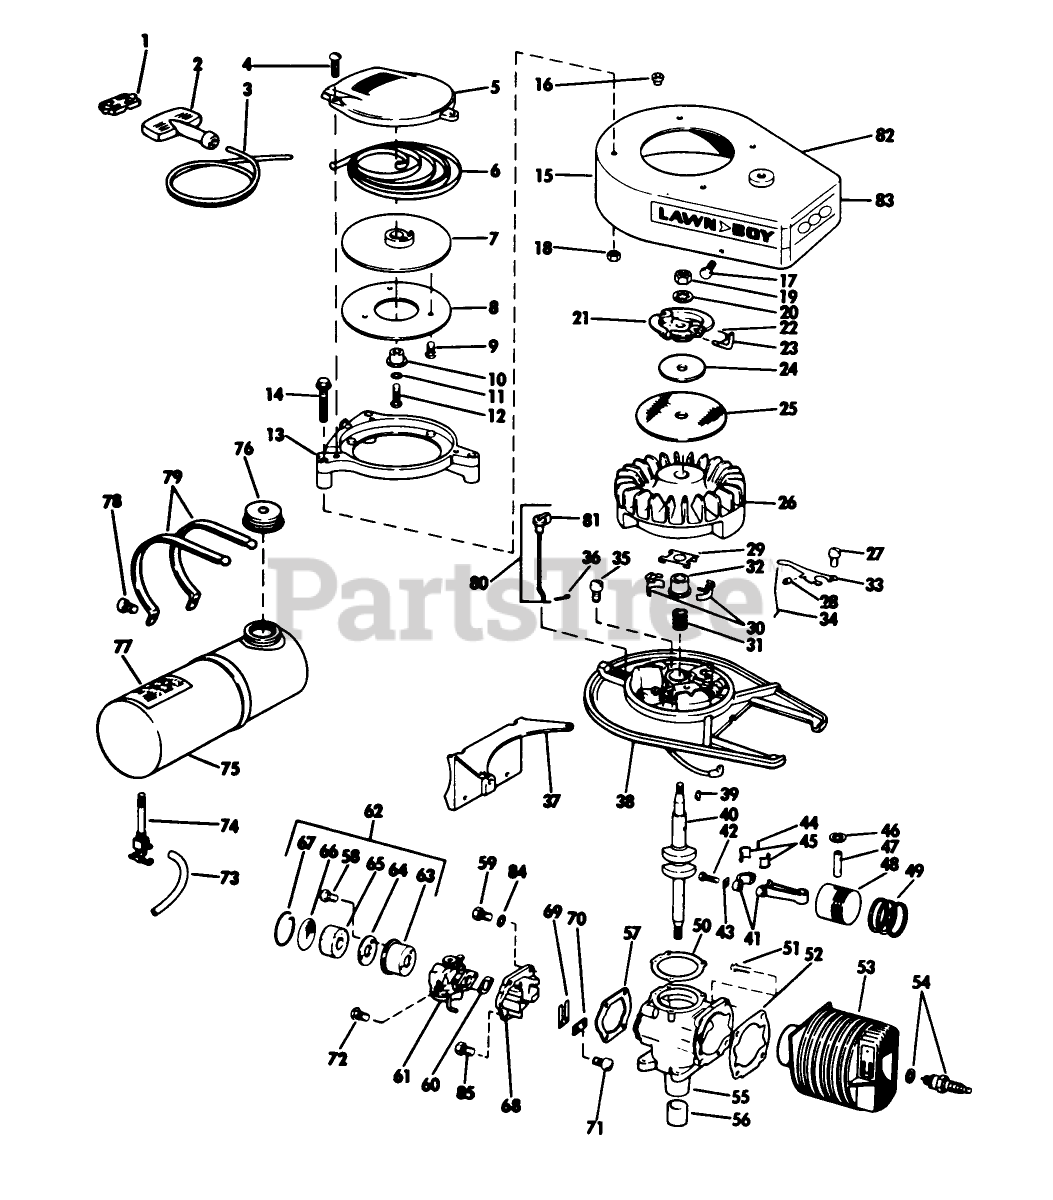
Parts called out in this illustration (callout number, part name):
6	RECOIL SPRING
17	SCREW S
23	Pin-Starter
28	WEAR BLOCK S
29	COLLAR S
33	GOVERNER LEVER AY
34	GOVERNOR ROD S
35	SCREW S
36	Cotter Pin
45	LINER ASM
46	RING-RETAINING
50	GASKET S
52	GASKET S
59	SCREW S
60	GASKET S
64	BACK-UP PLATE
65	ELEMENT
70	PLATE-BACKUP, REED
74	VALVE&SCREEN SM
80	Cotter Pin
81	KNOB, CHOKE BAR
85	SCREW S
